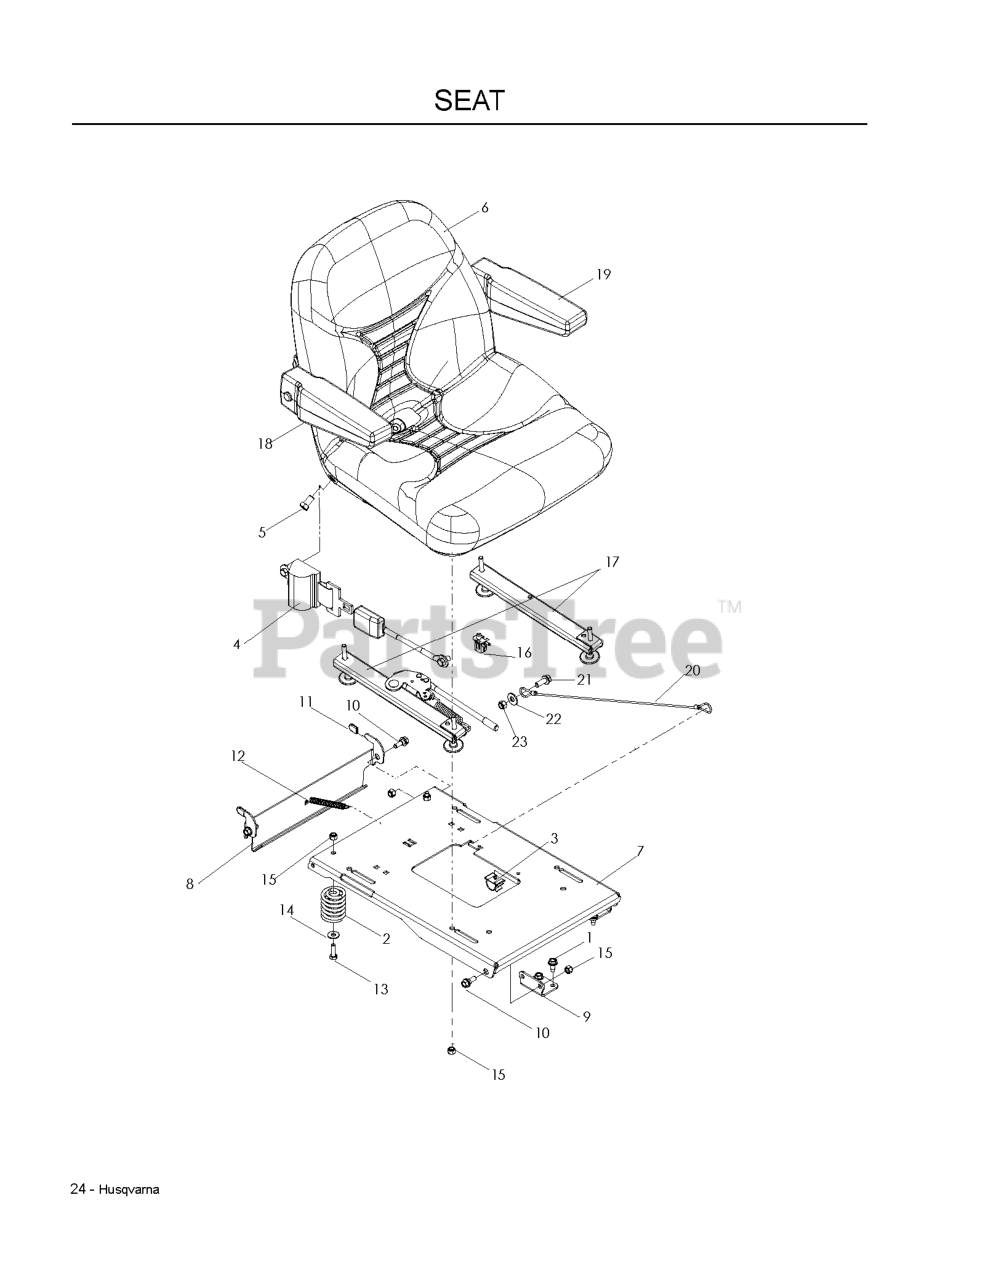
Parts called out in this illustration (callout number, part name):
1	BOLT 5/16-18 X 3/4
2	SPRING, SEAT
3	PUSH-MOUNT WIRE CLIP
4	SEAT BELT, RETRACTABLE
5	HCS 7/16-20 X .75 GD 5
6	SEAT
7	PAN, SEAT - BLACK
8	LATCH, SEAT - BLACK
9	PIVOT, SEAT PAN
10	SB 5/16-18 HEX HD GD5, BLK ZN
11	GRIP, VINYL, .09 X .495 X.75
13	HCS 5/16C X 1
14	WASHER 5/16 FLAT
15	NUT 5/16 NYLOC
16	SEAT SWITCH
17	TRACK ADJUSTMENT KIT
18	ARMREST KIT, RT SQUARE END
19	ARMREST KIT, LT SQUARE END
20	SEAT LANYARD
21	4CS 3/8C X 1 SERRATED HEAD
22	WASHER 3/8 FLAT
23	NUT 3/8-16 NYLOC
